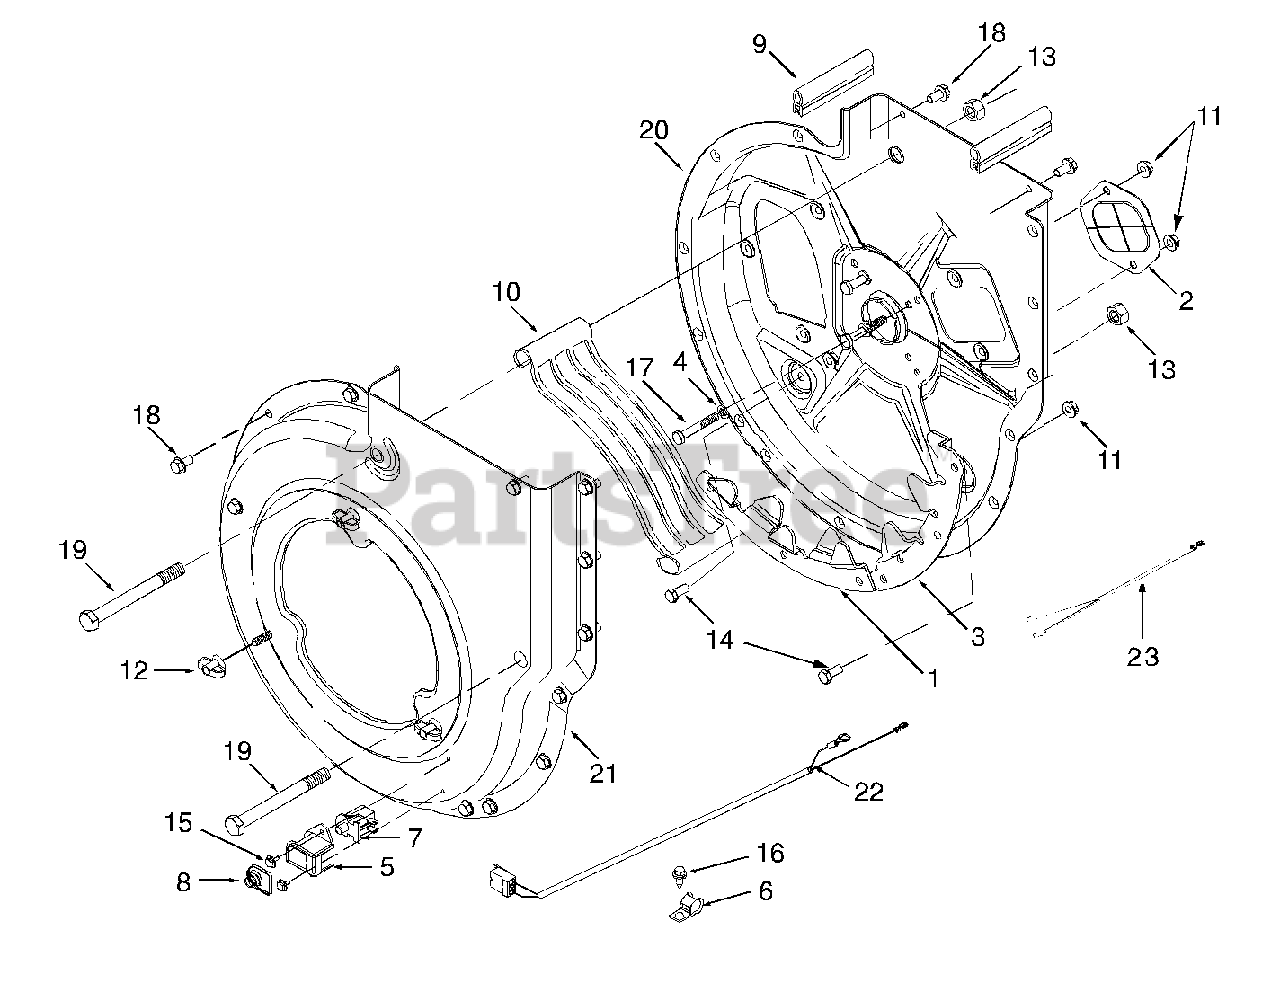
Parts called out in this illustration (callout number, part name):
4	Washer, Lock, 5/16
5	Cover, Safety Switch Mtg
6	Clamp
7	Switch, Snap Mount
8	Cover, Switch
9	Rubber Seal
10	Screen, Discharge
11	Nut, Hex Flange Lock, 5/16-18
12	Knob, 5/16-18
13	Nut, Hex Center Lock, 1/2-13
14	Screw, Hex Cap, 5/16-18 x .75GR5
15	Screw, Wash Hd Tapp #10-16
16	Screw, Wash Hd Tapp 1/4-141
17	Screw, Hex Cap, 5/16-18 x 2 GR5
18	Screw, Wash Hd Tapp 5/16-18
19	Screw, Hex Cap, 1/2-13 x 5.0
20	Housing Ass'y, Inner Flail
21	Housing Ass'y, Outer Flail
22	Harness, Wire
23	Adapter, Harness
